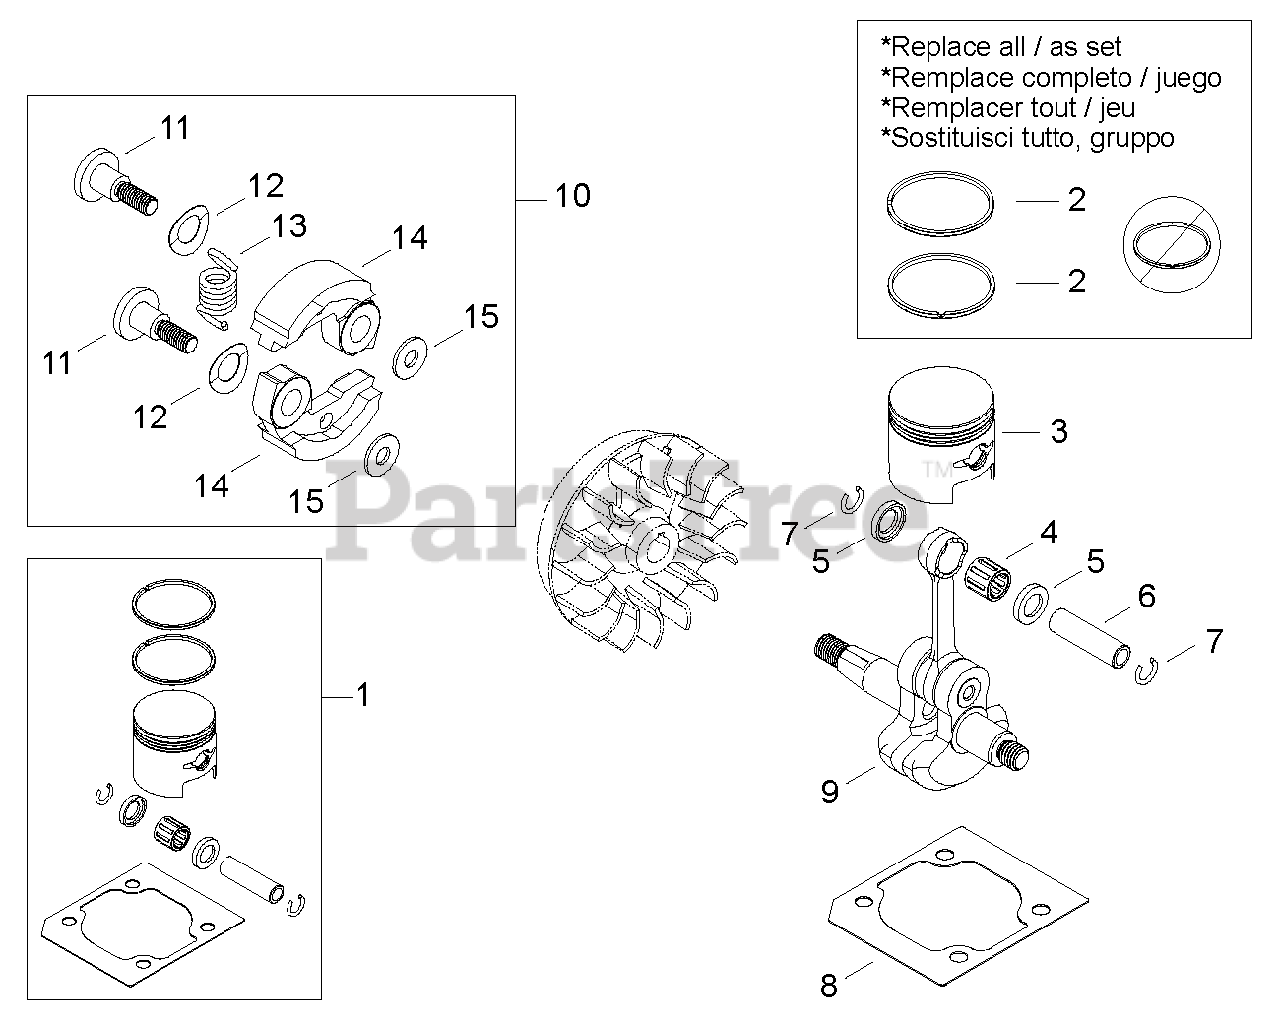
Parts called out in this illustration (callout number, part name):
2	RING, PISTON
3	PISTON
3-1	PISTON KIT
4	BEARING, NEEDLE - 8
5	SPACER, PISTON
6	PIN, PISTON
7	RING, RETAINING
8	GASKET, CYLINDER
9	CRANKSHAFT ASSY
10	CLUTCH ASSY
11	BOLT, CLUTCH
12	WASHER - SPRING
13	SPRING, CLUTCH
14	SHOE, CLUTCH
15	WASHER - 6
